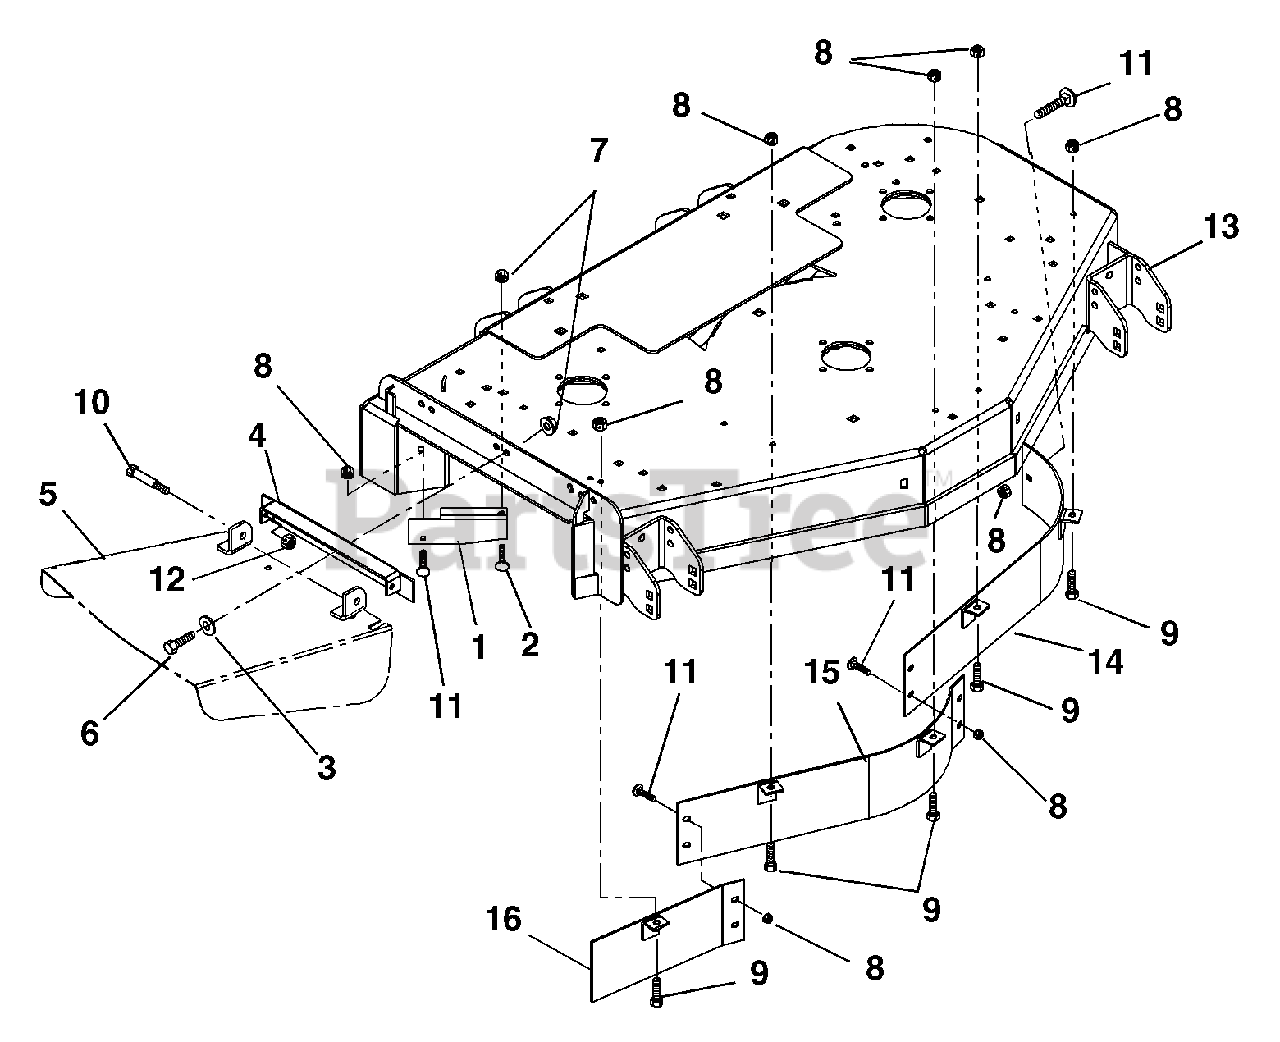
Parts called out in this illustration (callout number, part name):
1	DEFLECTOR - 52"/34"
2	@BLT-RDHDSQNK .38-16X1.00 G5YZ
3	@WSHR-FL-STL.38X.875X.083 YWZC
4	WMT, DISCH CHUTE BRKT - ORANGE
5	DISCH CHUTE - ORANGE
6	@BLT-HEX .38-16X1.00 GR5 YWZC
7	@NUT-LK-TOP-FLG .38-16 YWZC
8	@NUT-LK-TOP-FLG .31-18 YWZC
9	@BLT-HEX .31-18X.75 GR5 YWZC
10	BLT-SHLDR .38-16X.38 SKH
11	@BLT-RDHDSQNK .31-18X.75 G5YZ
12	@NUT-LK-CTR .38-16 YWZC
13	WMT, 52" MOWER DECK - ORANGE
14	BAFFLE - LEFT FRONT - 52"
15	BAFFLE - CENTER FRONT - 52"
16	BAFFLE - RIGHT FRONT - 52"
